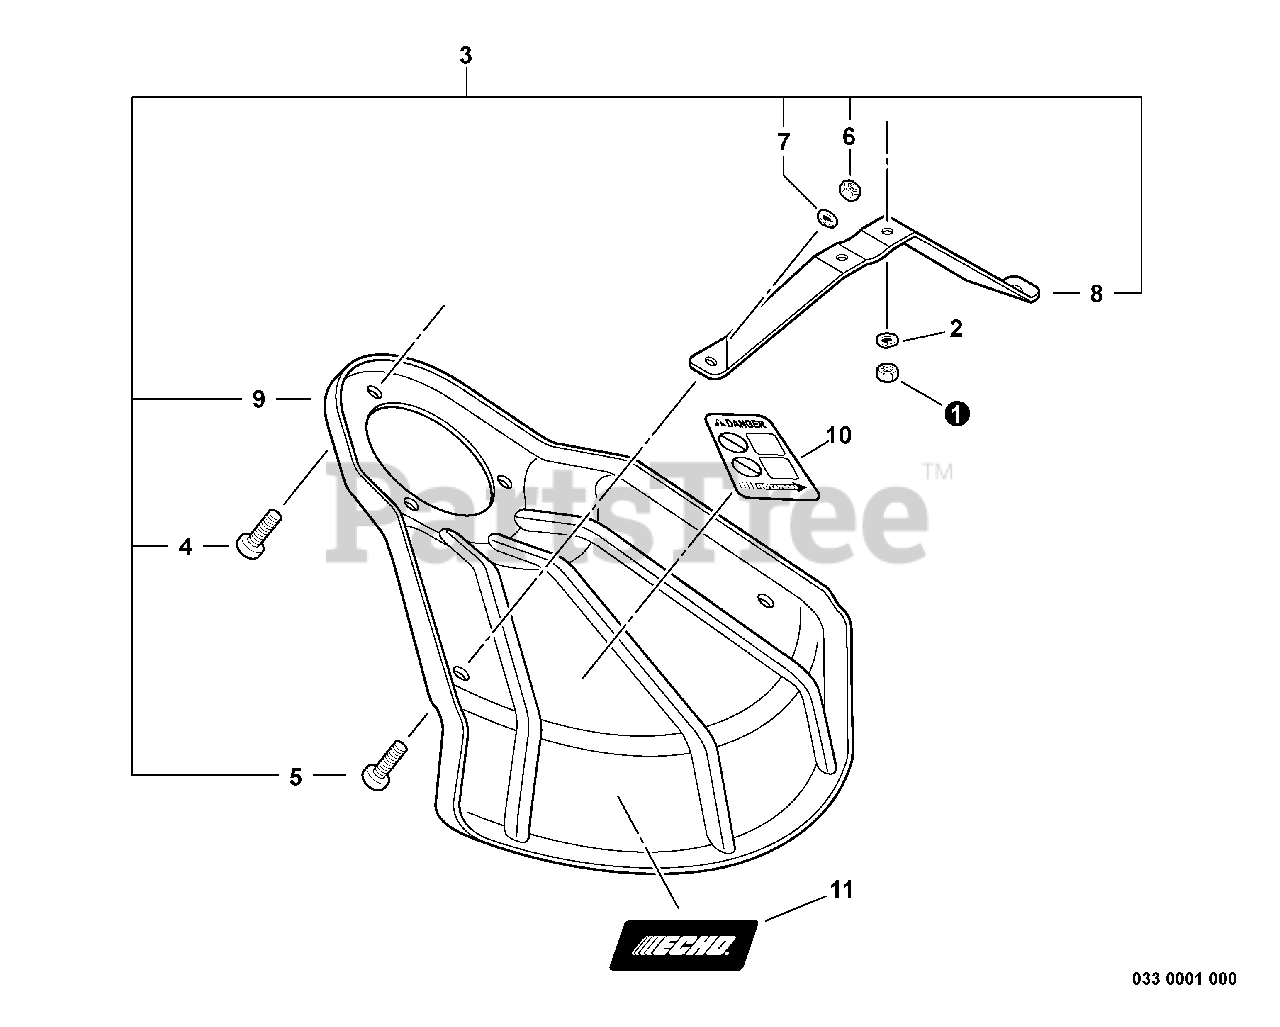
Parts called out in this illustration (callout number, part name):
1	NUT M5
2	WASHER, SPRING 5
3	SHIELD ASSY, METAL DEBRIS
4	SCREW 5×10
5	SCREW 5×8
6	NUT M5
7	WASHER, SPRING 5
8	BRACKET, SHIELD MOUNTING
9	SHIELD, METAL DEBRIS
10	LABEL, DANGER
11	LABEL, ECHO
